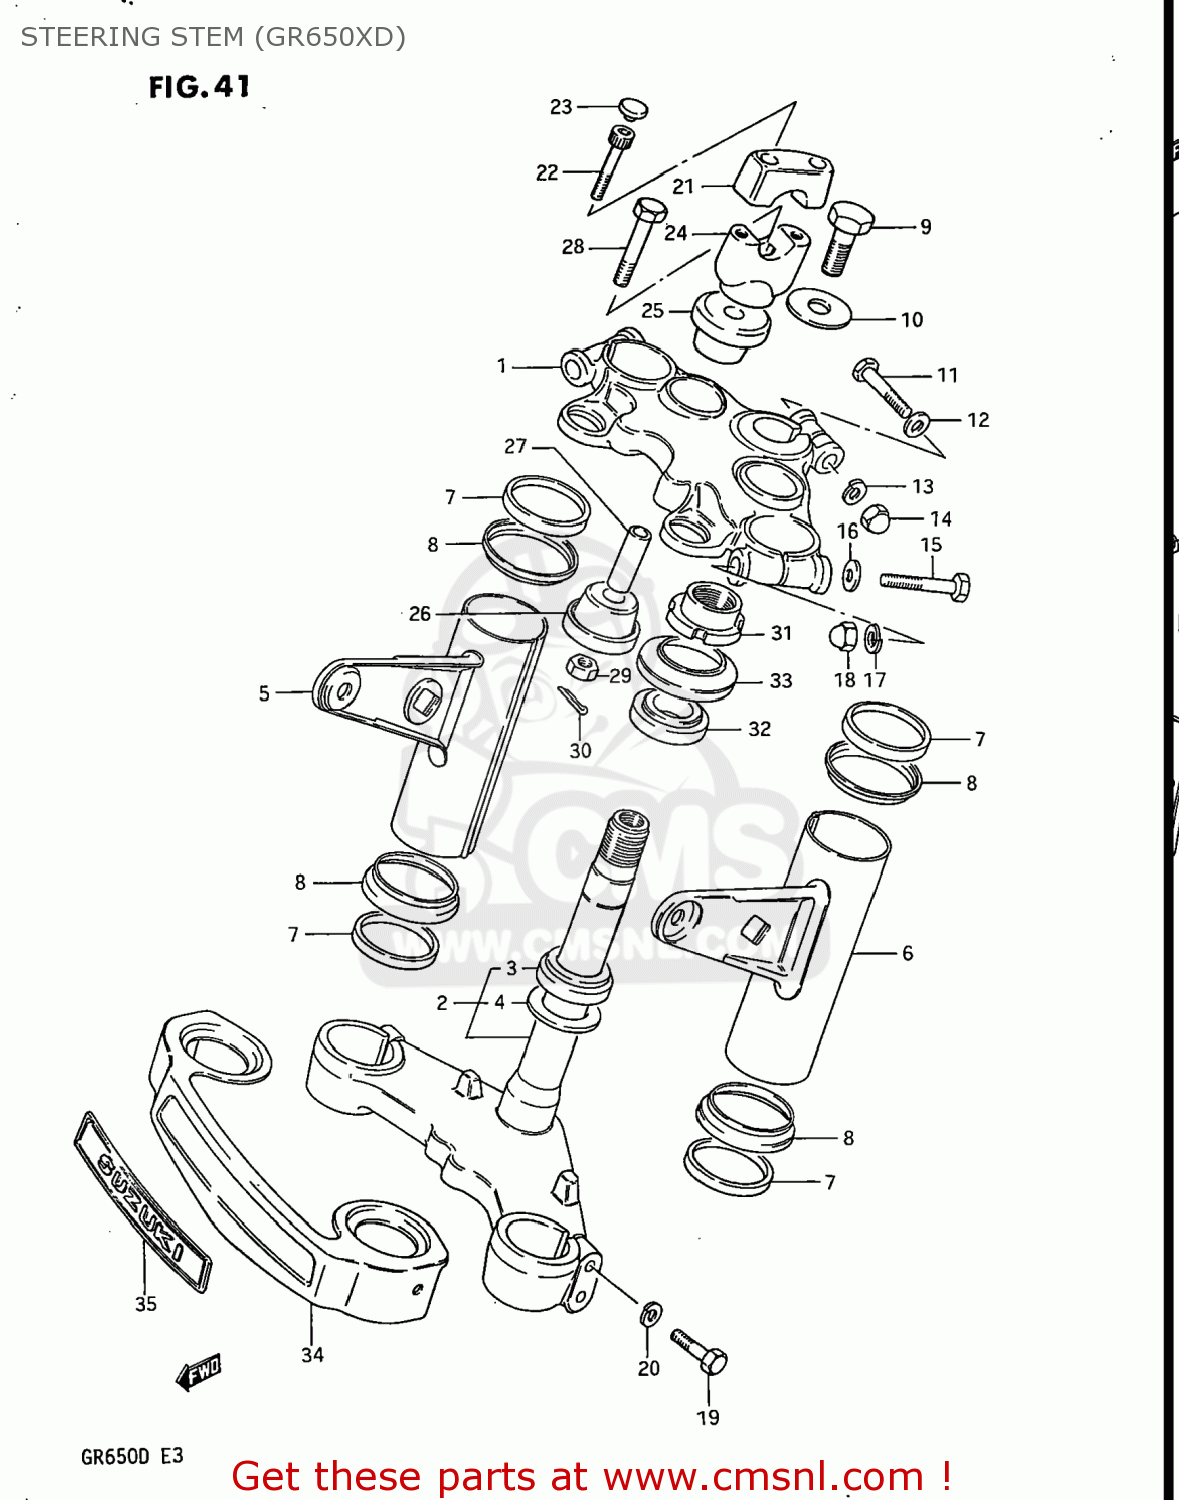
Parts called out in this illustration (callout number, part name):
1	HEAD,STEERING STEM
2	STEM,STEERING
3	BEARING
4	WASHER,THRUST
5	BRACKET COMP,HEADLAMP
6	BRACKET,HEADLAMP,LEFT
7	CUSHION,HEADLAMP BRACKET
8	CAP,HEADLAMP BRACKET
9	BOLT,STEERING STEM HEAD
10	WASHER
11	BOLT 8X50
12	WASHER
13	LOCK WASHER
14	NUT,M8X1.25X12
15	BOLT 10X55
16	WASHER 10MM
17	LOCK WASHER
18	NUT
19	BOLT 8X40
20	LOCK WASHER
21	CLAMP,HANDLE BAR,UPPER
22	BOLT
23	CAP(OD:14.5)
24	CLAMP,HANDLE BAR,LOWER
25	CUSHION,LWR
26	CUSHION,LWR
27	SPACER(10.2X14X46)
28	BOLT(10X78)
29	NUT
30	COTTER PIN
31	NUT,STEERING STEM
32	TAPER,ROLLER BEARING
33	DUST SEAL,STEERING UPR
34	COVER,FRONT FORK
35	EMBLEM,FRONT FORK COVER
